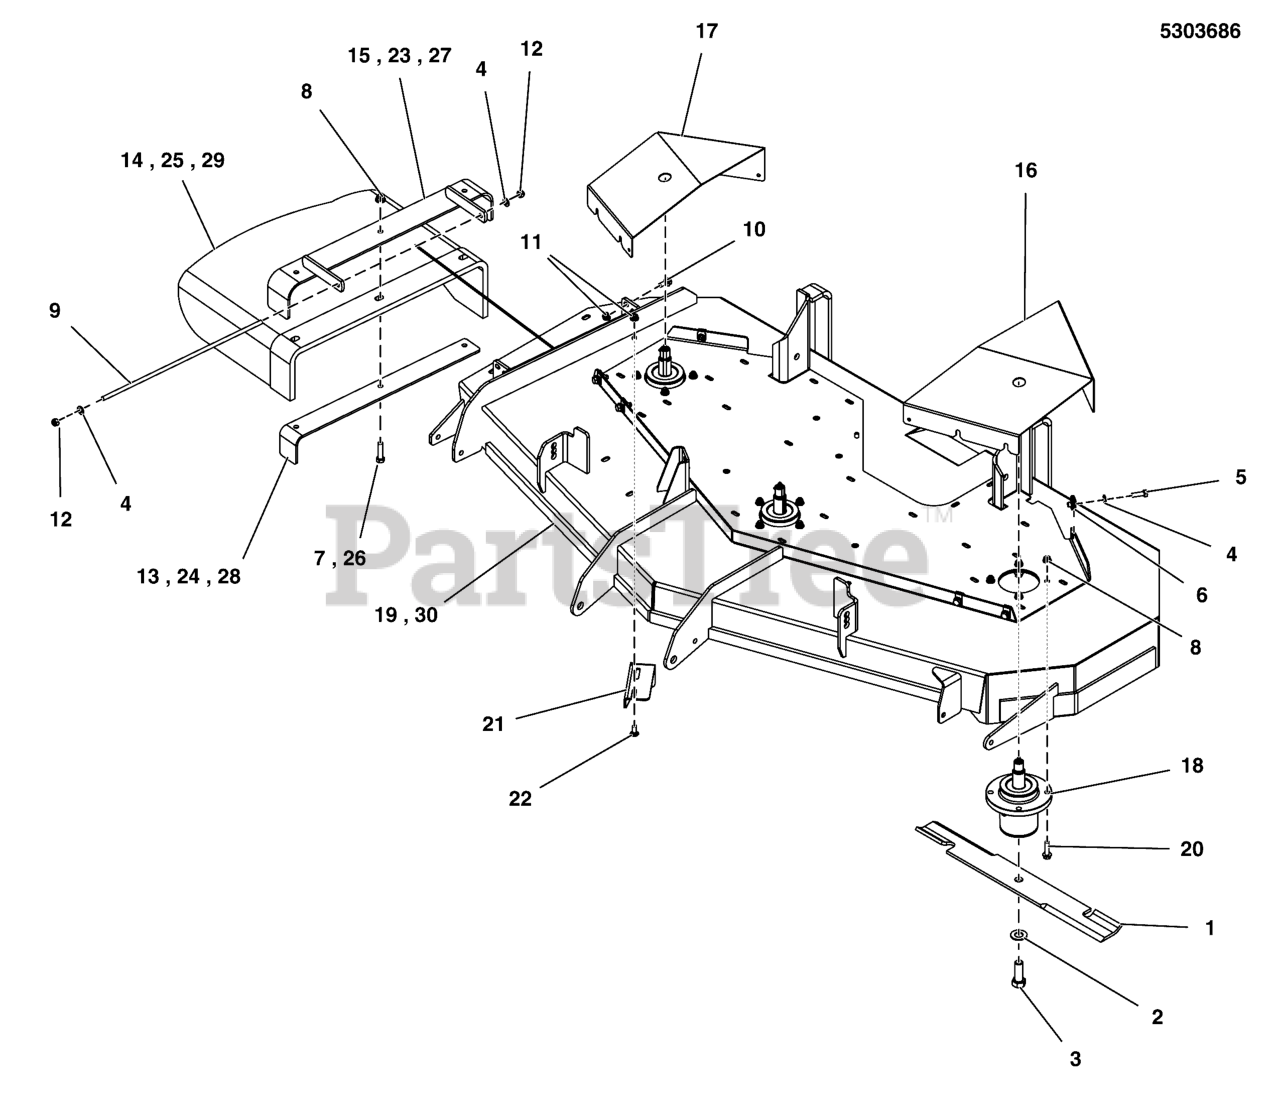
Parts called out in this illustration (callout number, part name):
1	BLADE SET, 61 DECK (3)
2	WASHER, BLADE BOLT, 9/16" F436, CZ
3	BOLT, 5/8-11 X 1-3/4 GD8
4	WASHER, 5/16" SAE
5	BOLT, 5/16-18 X 3/4 GD5
6	BODY CLIP, 5/16-18-7GA MATERIAL
7	BOLT, 3/8-16 X 1-1/2" GD5 CZ
8	NUT, 3/8-16 HEX NYLOCK FLANGE
9	ROD, MOUNT, CHUTE 61, CZ
10	BOLT, 5/16-18 X 3/4 GD5
11	NUT, 5/16-18 HEX NYLOCK FLANGE
12	NUT, 5/16-24 HEX NYLON LOCK
13	SUPPORT, DISCHARGE CHUTE, 61/72 - BLK
14	CHUTE, BEND, RUBBER, 125 DEG (5103719)
15	WELD, FRAME, CHUTE, 61" - BLK
16	GUARD, DECK, 61, LH - RED
17	GUARD, DECK, 61, RH - RED
18	ASSM, SPINDLE, LOW PROFILE
19	DECK SHELL W/ DECALS, 61, SW35 (5411927D)
20	BOLT, 3/8-16 X 1-1/4, FLANGE, GD5, CZ
21	PLATE, DEFLECTOR - BLK
22	BOLT, 5/16-18 X 3/4, CARRIAGE
23	WELD, MOUNT, DISCHARGE CHUTE - BLK
24	CHUTE, RUBBER DISCHARGE (5104442)
25	SUPPORT, DISCHARGE CHUTE - BLK
26	BOLT, 3/8-16 X 1-1/2, CARRIAGE, GD5, CZ
27	MOUNT
28	SUPPORT, DISCHARGE CHUTE - BLK
29	CHUTE, RUBBER DISCHARGE (5104442)
30	DECK SHELL W/ DECALS, 61, SW35 (5414555D)
